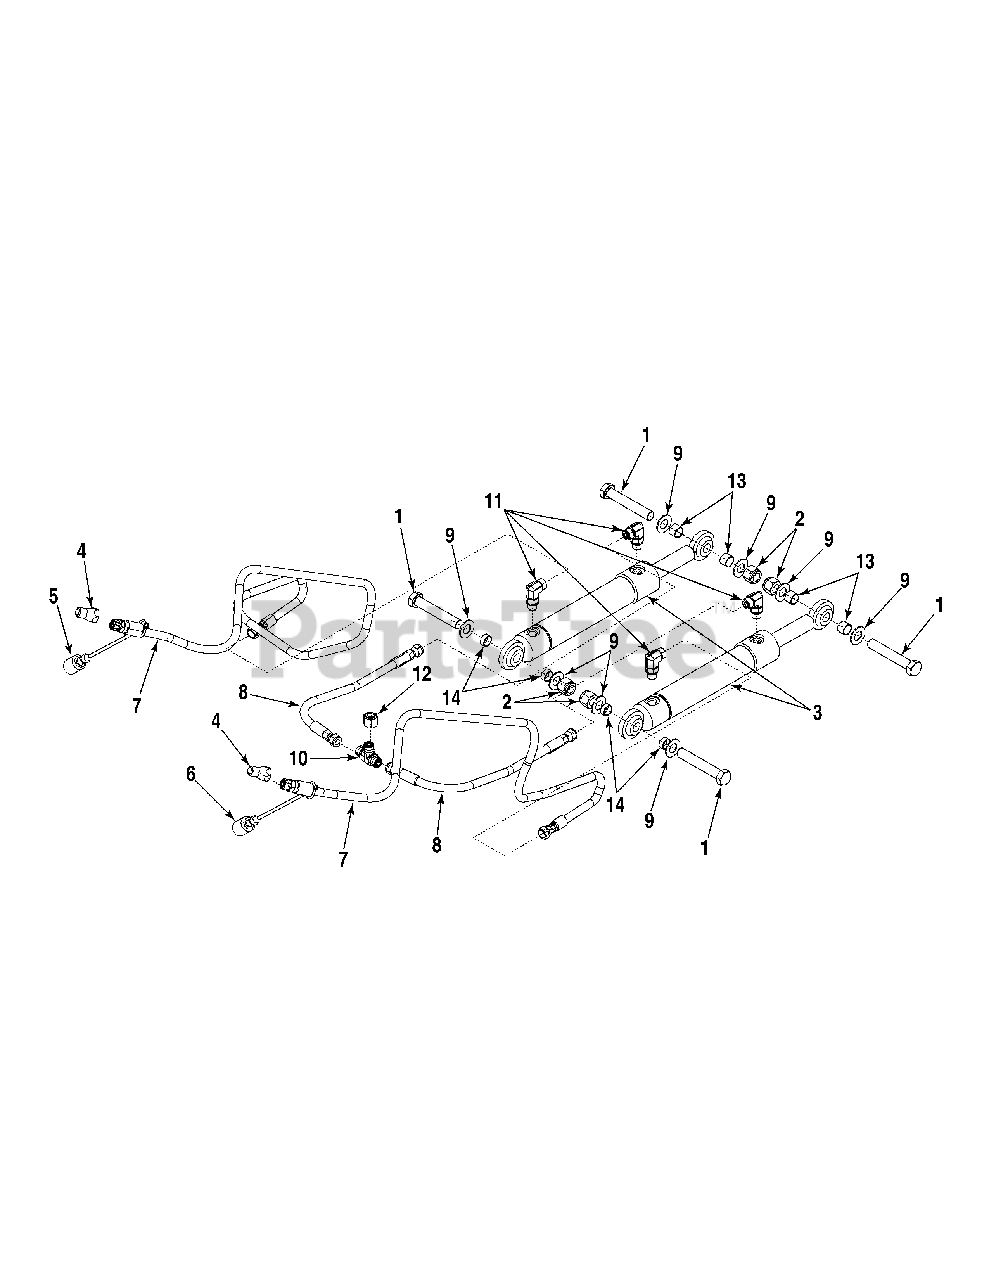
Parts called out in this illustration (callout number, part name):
1	Screw, Hex Cap, 5/8-11 x3.75 Gr5
2	Nut, Hex Insert Lock 5/8-11, Gr5
3	Cylinder, Hitch Angle
4	Coupling, Hydraulic Male, 9/16-18
5	Plug, Hyd. Coupler, Green
6	Plug, Hyd. Coupler, Yellow
7	Hose, Hydraulic, 60.0
8	Hose, Hydraulic
9	Washer, Flat, .65 x 1.25 x .075
10	Fitting, Standard Male Tee, 3/8 ORFS
11	Fitting, 90 Degree, 3/8
12	Cap, Fitting, 3/8
13	Hub, Angle Cylinder, Long
14	Hub, Angle Cylinder, Short
